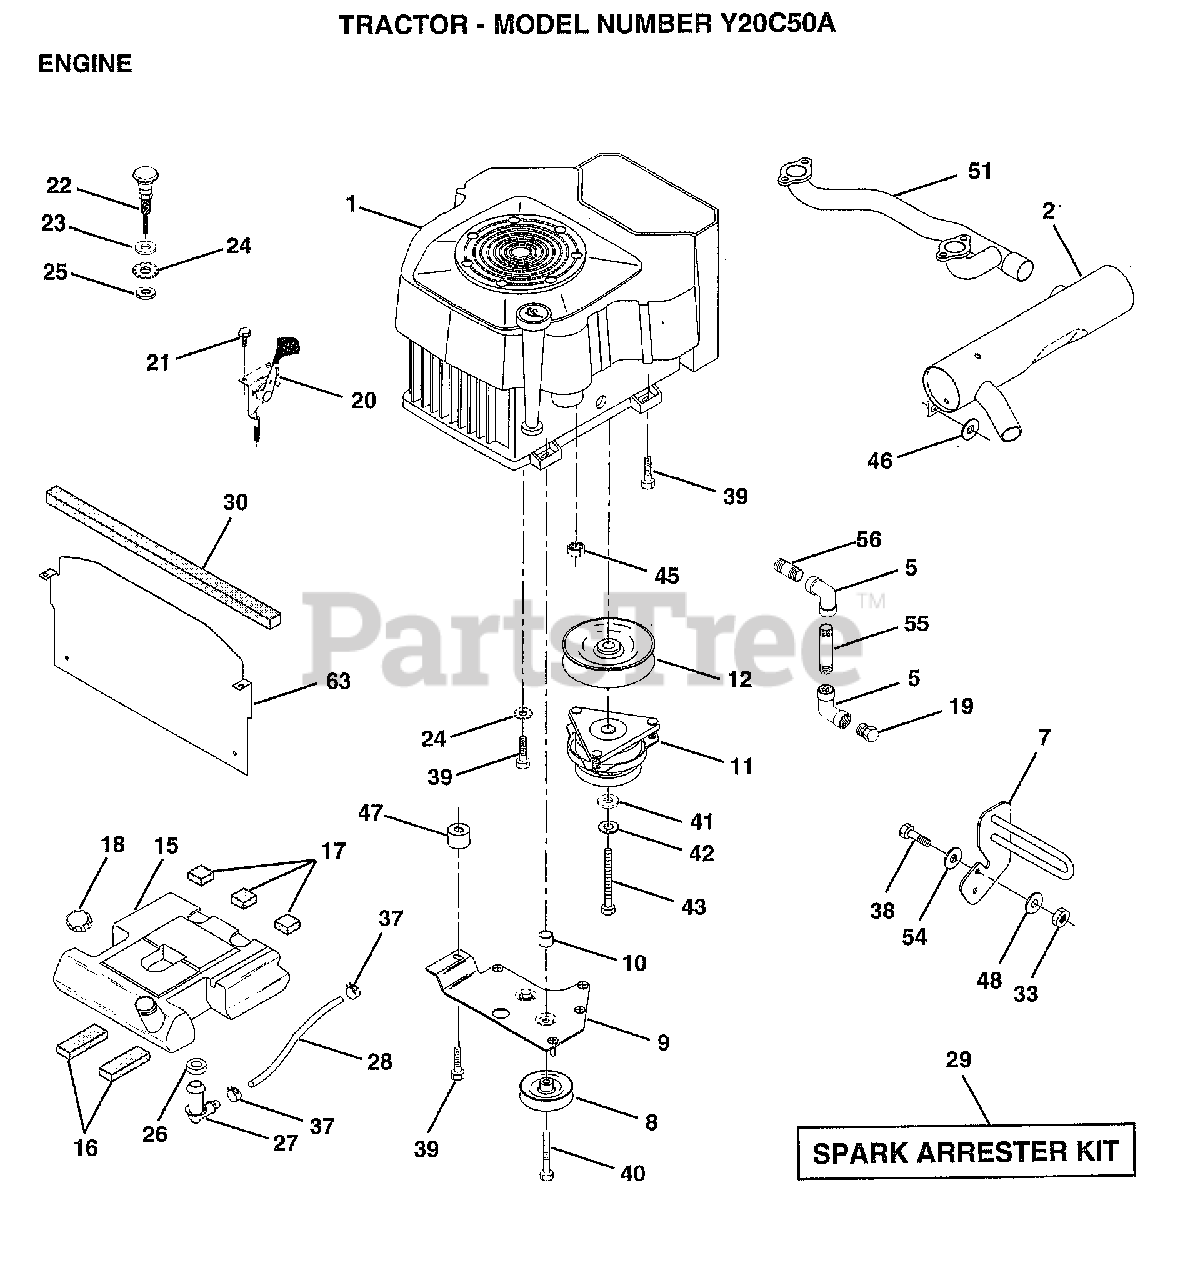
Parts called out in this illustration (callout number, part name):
5	ELBOW
10	BUSHING.
12	PULLEY.ENG.CLUTCH
16	PAD IDLER TI
17	PAD-SPACER LT
18	CAP ASM FUEL
19	PLUG T
21	SCREW LT
22	CHOKE CONTROL
23	WASHER
24	LOCKWASHER
26	BUSHING OUTLET T
27	STEM.TANK.FUEL
29	SPARK ARREST KIT
30	FOAM-STRIP LT
33	NUT
37	HOSE CLAMP
38	"BOLT,HEX"
39	SCREW.3/8-16X2.25
40	SCREW.TT.3/8-16X4
41	WASHER
42	LOCKWASHER
43	BOLT.7/16-20X4.25
45	NUT
46	WASHER HYT
47	SPACER.ENGINE
48	WASHER T
54	WASHER
56	NIPPLE.PIPE
63	HEAT.SHIELD.VGT.
